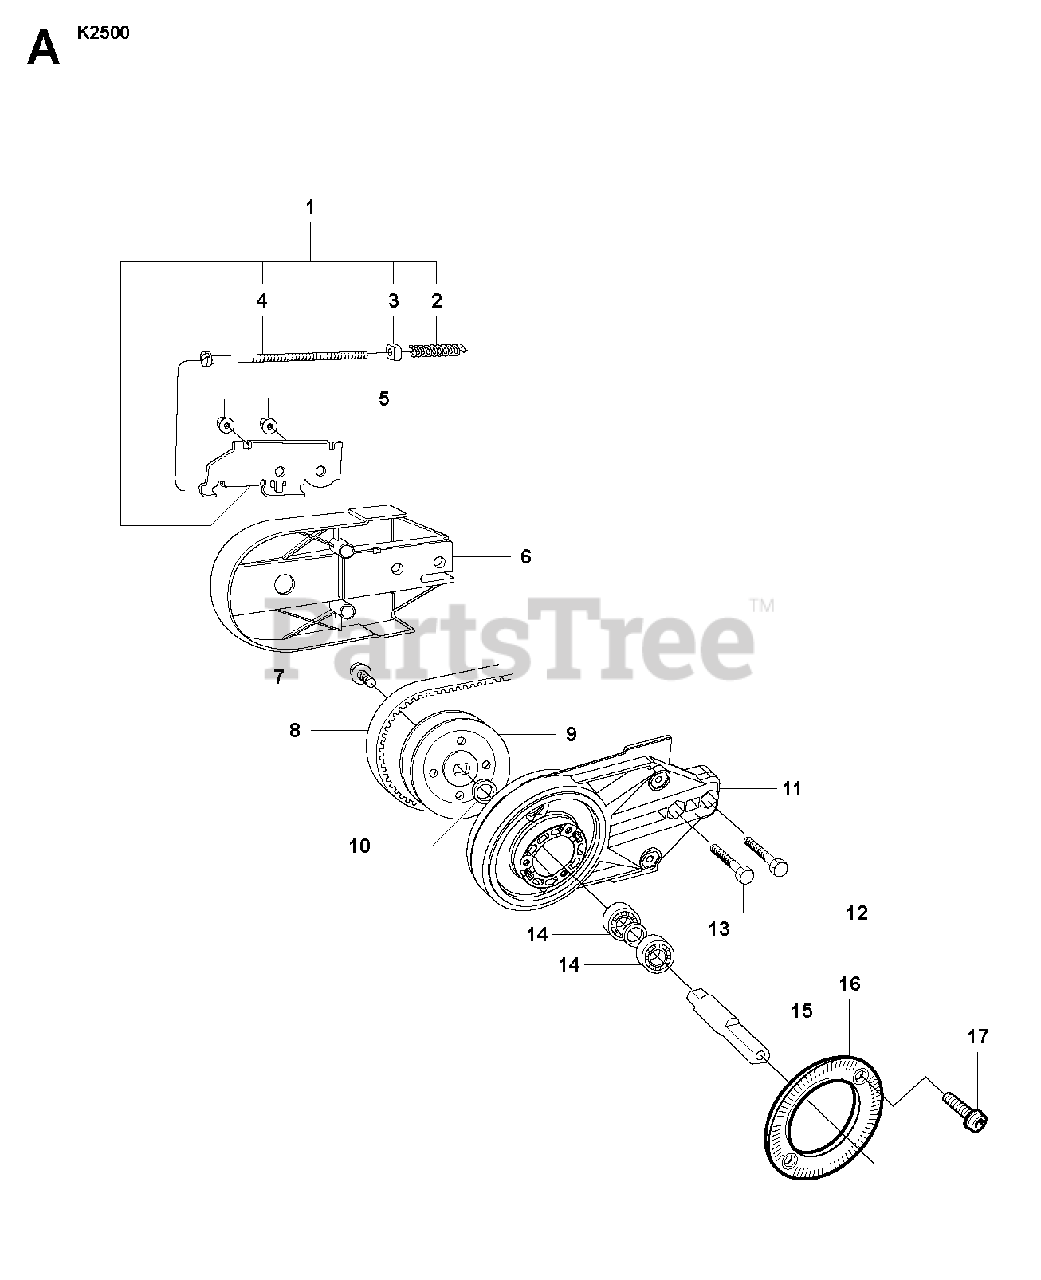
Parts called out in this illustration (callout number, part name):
1	BELT TENSIONER ASSYIncl. 2, 3, 4
14	BALL BEARING
17	SCREW IHSCFM
